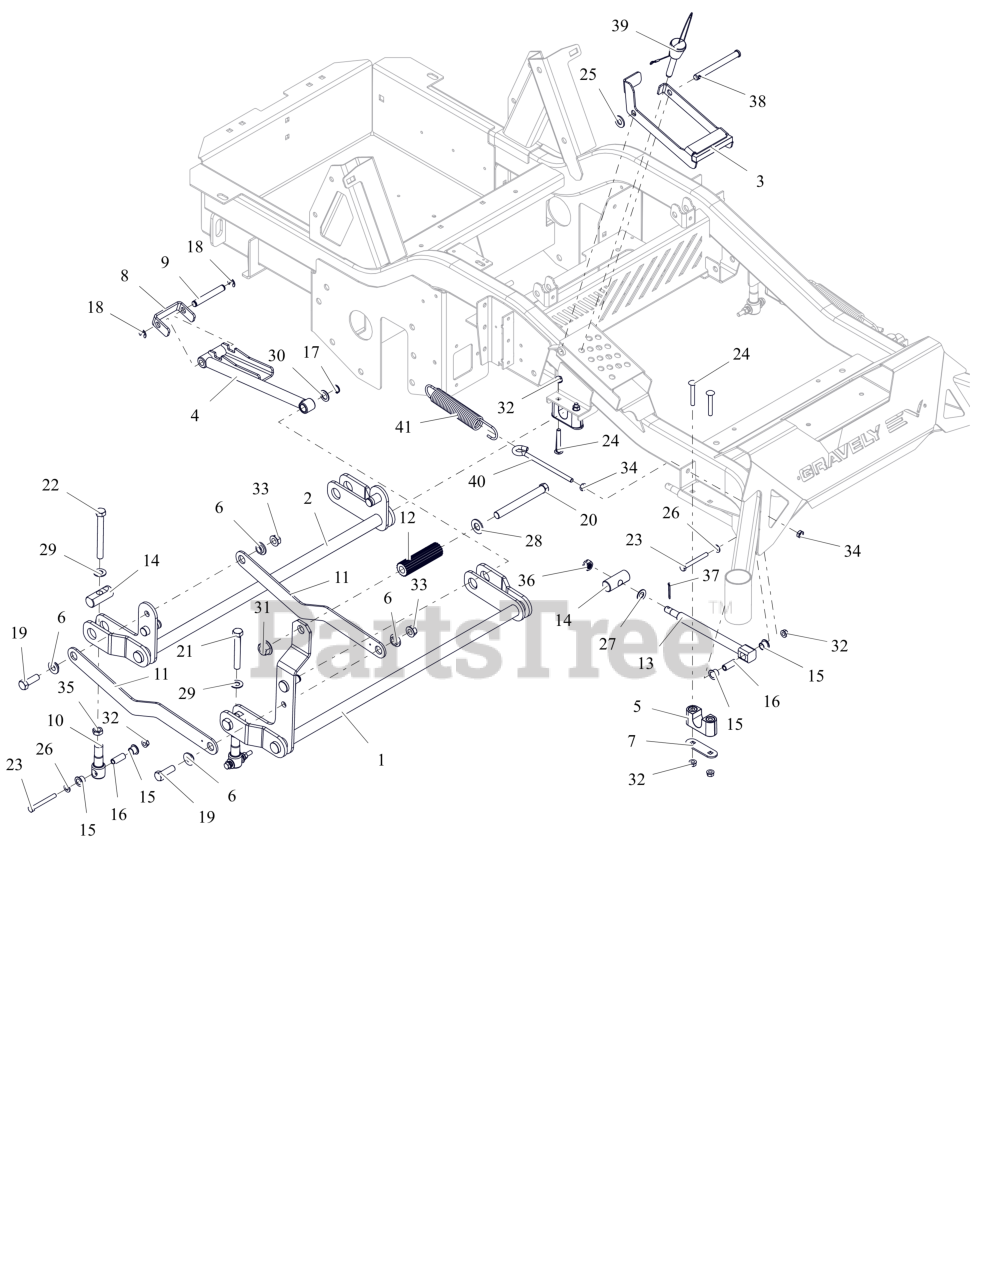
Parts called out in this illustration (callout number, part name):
1	WLDMT, FRONT DECK LIFT PIVOT
2	WLDMT, REAR DECK LIFT PIVOT
3	WLDMT, HOC TRANSFER LOCK (BLACK)
4	WLDMT, HOC LIFT ARM (BLACK)
5	ASM-BUSHING, DECK LIFT
6	BSHG-FLG .515X.750X.310X1.120
7	PLATE, BEARING SUPPORT
8	BRKT, HOC LINE
9	ROD, HOC PIVOT
10	LINK, DECK LIFT FORMED
11	LINK, DECK
12	ROD, FOOT PEDAL (BLACK)
13	DRAG,LINK-HD
14	PIN, DECK LIFT
15	BSHG, FLANGED .50X.625X.50X.062
16	SPCR, .31X.50X1.265
17	RG-RTNG-EXT .625X.050
18	RG-RTNG-EXT .500X.042 (E)
19	BLT,HEX .50-13X1.50 G5 ZCC
20	BLT, HEX .62-11X5.50 G5 FBP
21	BLT, HEX 0.5-13X3.5F GR5 ZCC
22	BLT, HEX .50-13X4.50F G8 ZCC
23	BLT, HEX .31-18X2.75 G5 ZCC
24	BLT, RHSSN.31-18X2.25 G5 ZCC
25	WSHR,FLT .531X1.062X.095 ZCC
26	WSHR,FLT .344X.688X.065 ZCC
27	WSHR, BLVL .505 X 1.000 X .073 ZCC
28	WSHRFLT 5/8SAE CARBHARD FBP
29	WSHR, FLT .557X1.040X.102 ZCC
30	WSHR, FLT .630X1.005X.062 ZCC
31	NUT,FLG-TOP LK .625-11 FBP
32	NUT,LK-CTR-FLG .31-18 GF ZCC
33	NUT-LK-CTR-FLG .500-13 GG ZCC
34	NUT-JAM .375-16 G2 ZCC
35	NUT-JAM .500-13 G2 ZCC
36	NUT-SL .50-13
37	PIN,CTR.12X1.25EXTPRSQCT ZC120
38	PIN, SLIC-.500X4.97X4.55 -ZC
39	PIN, MAGNETIC .50X2.50
40	BOLT,.38-16 X 5.25-.62 DIA EYE
41	SG-TENS .162X1.25X8.25 WLD 25
